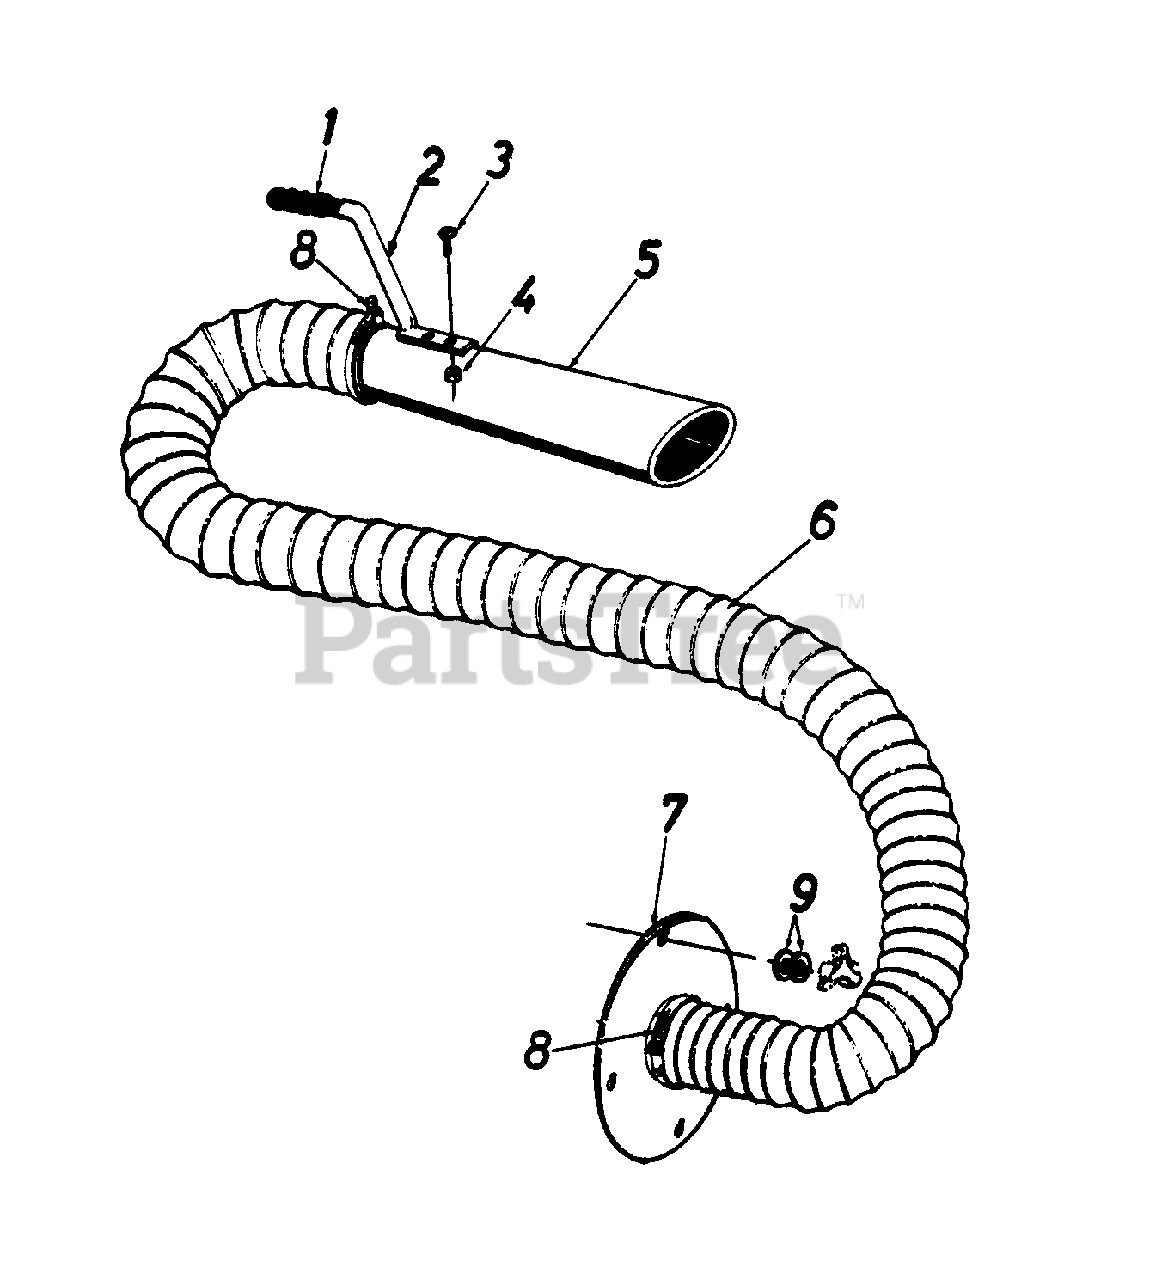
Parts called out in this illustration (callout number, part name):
1	Handle Grip
4	Hex Nut 10-24 Thd.
5	Hose Nozzle
6	Flexible Hose 4" Dia. x 10' Lg.
9	Flat Washer .34 I.D. x 1.12 O.D.
